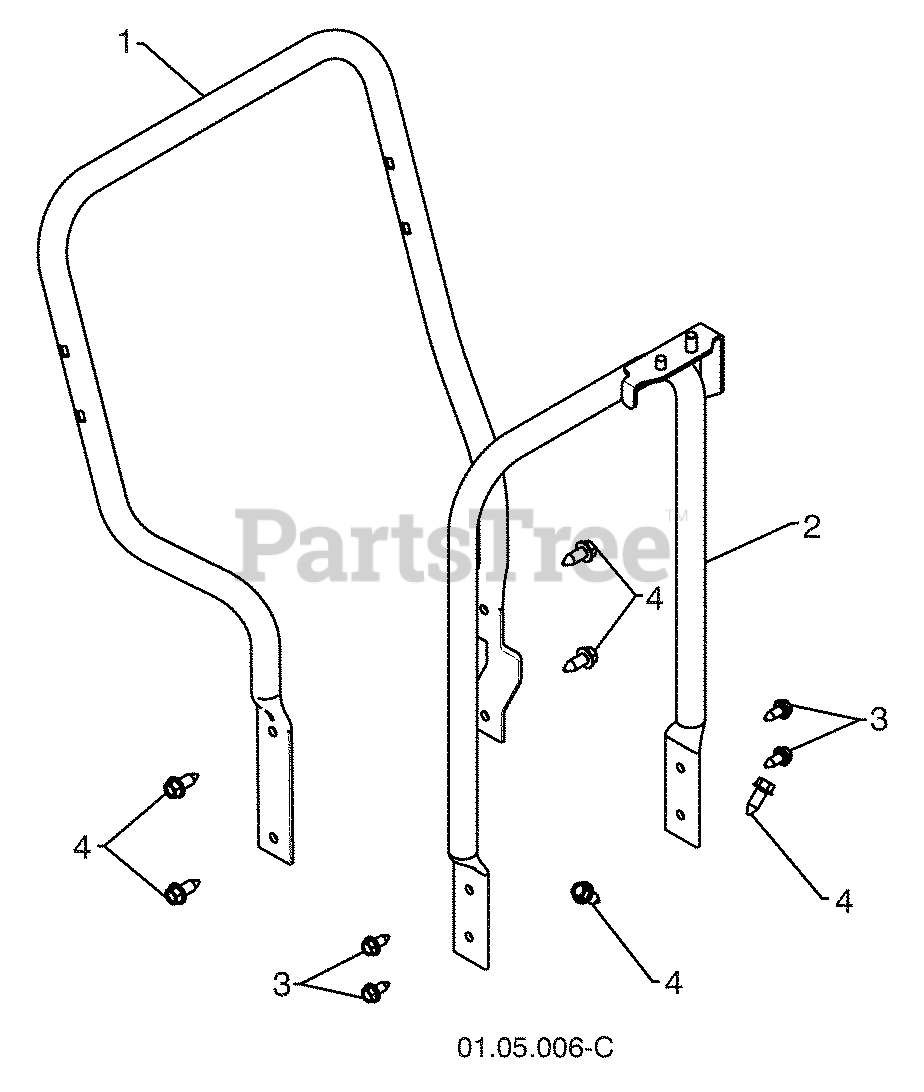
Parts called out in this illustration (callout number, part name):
1	LOWER TUBE GRAY
2	PIVOT SUPPORT
3	BOLT 5/16--18 X .75
4	SCREW 3/8--16 X 1.00
